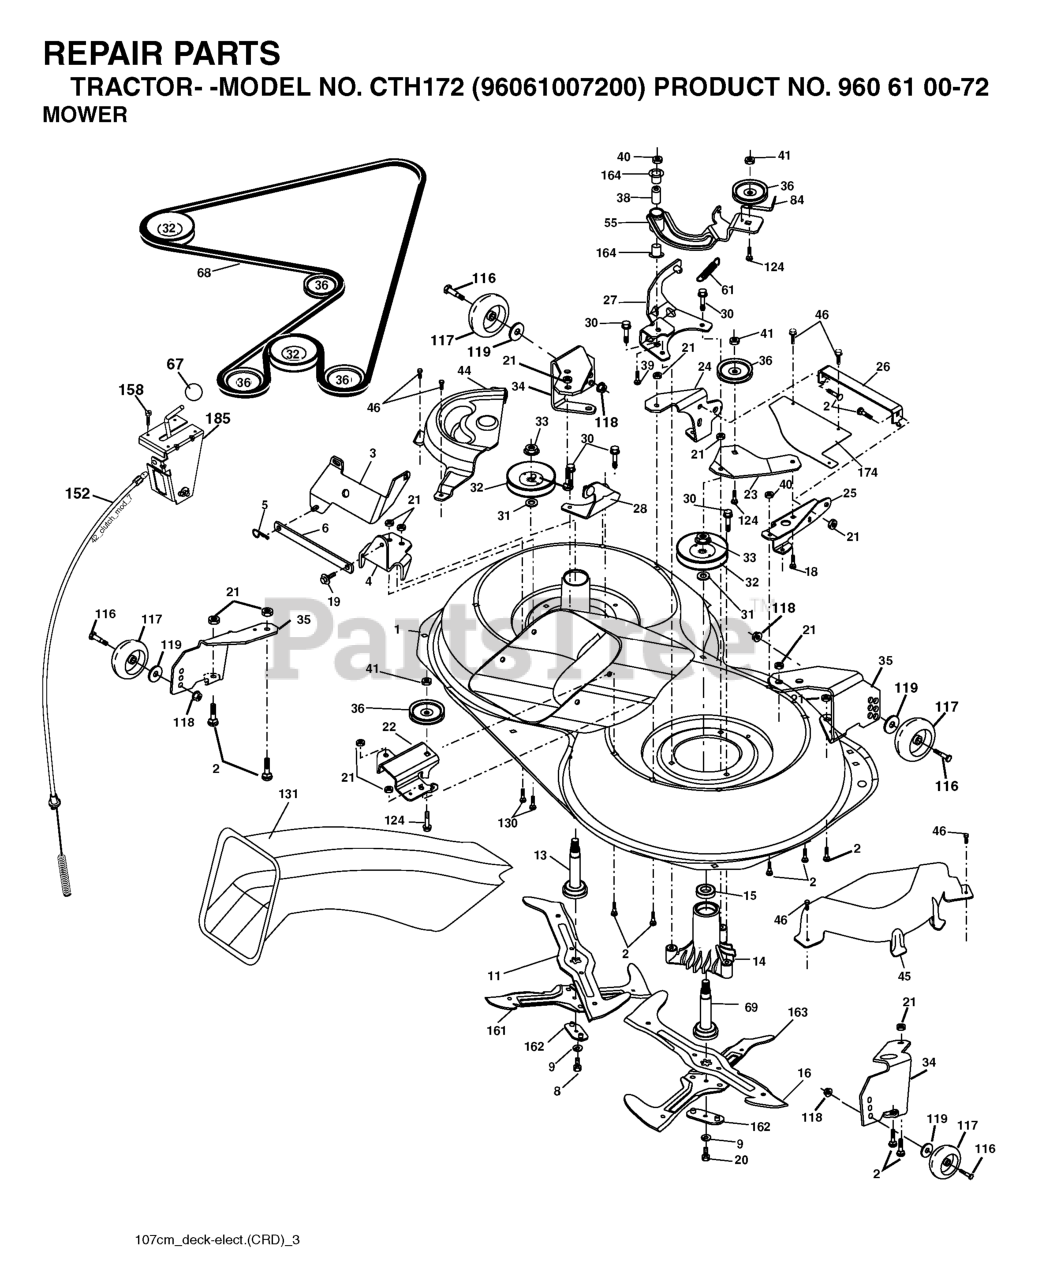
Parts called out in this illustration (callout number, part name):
1	Housing Asm. Mower 107 CRD
2	RP BOLT 5/16-18 X3/4 ZN/YEL GR
5	RETAINER-SPRNG RB
6	BAR.SWAY.92.CRD
8	BOLT.3/8-24X1.25 GR8
9	LOCKWASHER
11	BLADE.3N1.LH.CRD
13	SHAFT ASM VENT
14	HOUSING.MANDREL.VENTED (MACHD)
16	BLADE.3N1.RH.CRD
19	BOLT SHD 5/16-18
20	BOLT.3/8-24X1.25GR8. LHTHRD
21	LOCKNUT
22	BRACKET.IDLER.RR.107.CRD
25	BRACKET RF
26	SUPPORT
28	BRACKET
30	SCREW, WASHER HEAD
31	WASHER.SPACER.MANDREL
32	PULLEY.MANDREL.4.80 PD.2006
33	NUT.FLANGE.LOCK.TOP
34	BRACKET
35	BRACKET
36	PULLEY.IDLER.4.25
41	NUT LOCK FLG 3/8-16 UNC
45	COVER.MANDREL.RH.CRD
46	SCREW.1/4-20X5/8
55	ARM.IDLER.107.CRD
61	SPRING
67	KNOB T (3/8 HOLE)
68	HEX-BELT 107 MOWER
69	SHAFT.ASM.W/LWR.BRG.RH.THREAD
84	KEEPER, BELT IDLER
116	SHOULDER BOLT
117	RP WHEEL. GUAGE RALLY
118	LOCKNUT
119	WASHER.5/16.FLAT.STE.STD.
124	BOLT.3/8-16X1.50
130	BOLT.CARR.SQNK.5/16-18UNC.X3/4
131	CHUTE BAGGER
158	SCREW
163	BLADE.CROSS.RH.CRD.107
164	BRNG T
174	PLATE
185	HEAD ASM. CABLE CLUTCH
